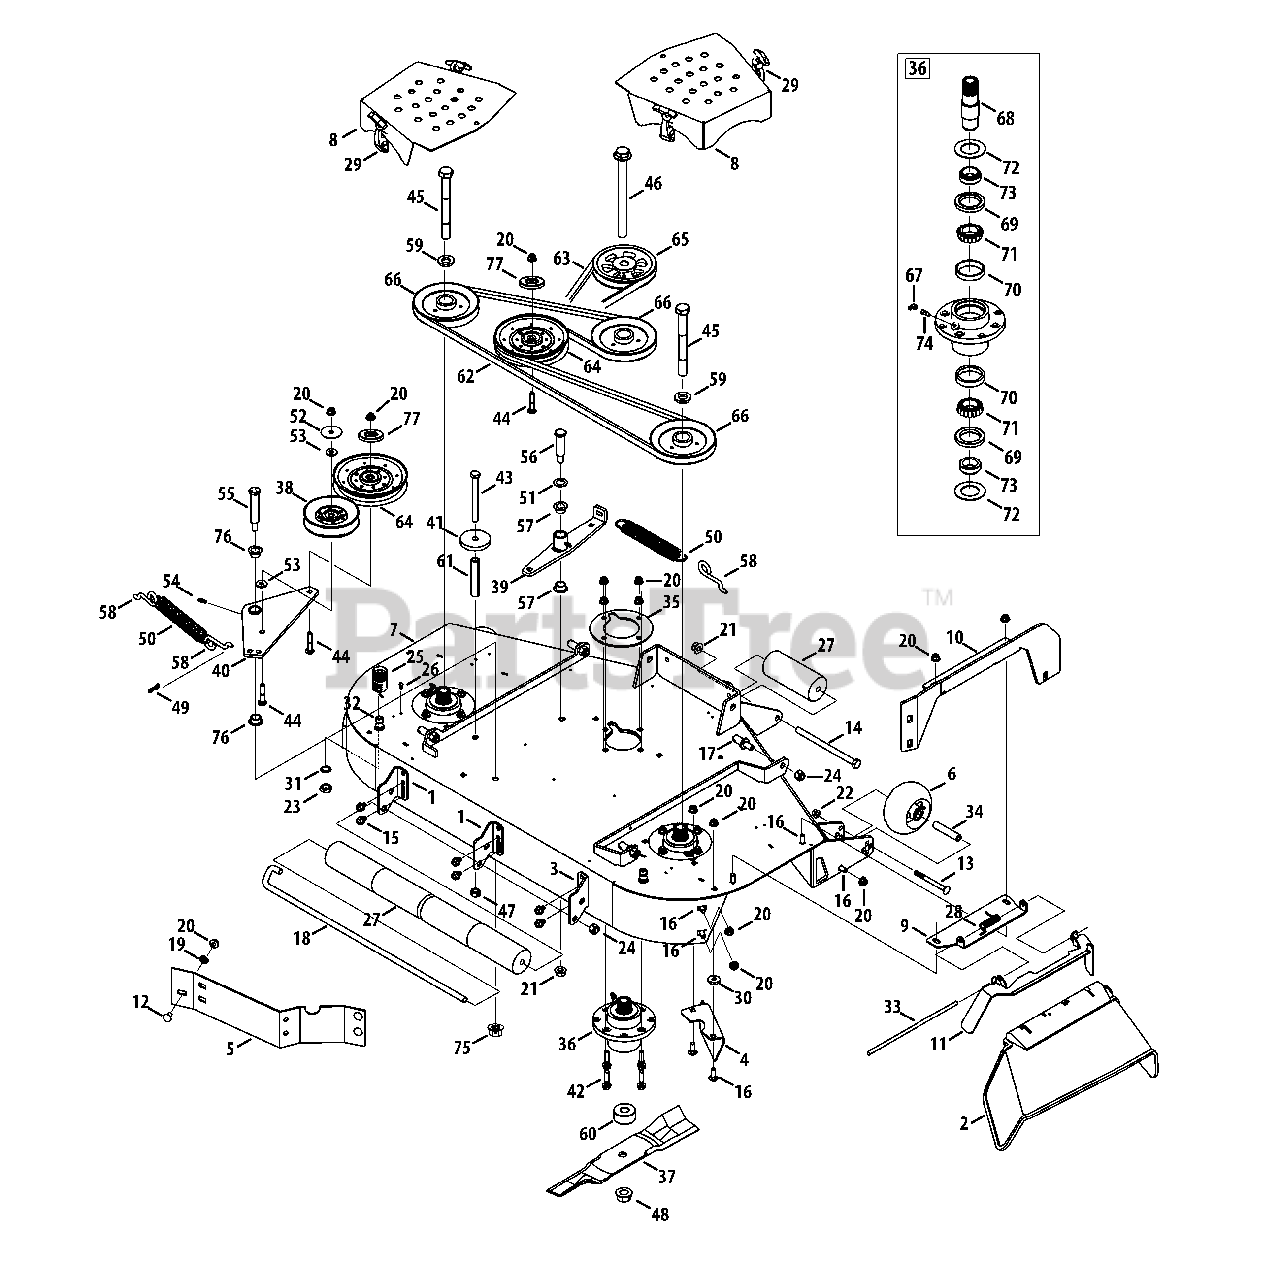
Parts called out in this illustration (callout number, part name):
2	Chute Deflector
5	Baffle, 48" Adjustment
6	Complete Wheel, 5.00 Dia.
7	48" Deck
8	Deck Belt Cover
9	Chute Deflector Bracket
10	Deck Support Plate
11	Chute Extension Bracket
12	Carriage Bolt, 3/8-16 x .750
13	Carriage Bolt, 3/8-16 x 4.00
14	Hex Cap SCrew, 1/2-13 x 7.50
15	Screw, 3/8-16 x .500
16	Carriage Bolt, 3/8-16 x 1.00
17	Pin, 1/2-13 x .625 x 1.2
18	J-Hook w/ Threaded Roller
19	Push Nut, 3/8
20	Nut, 3/8-16, Flangelock
21	Nut, 1/2-13, Flangelock
22	Nut, 3/8-16, Centerlock
23	Hex Nut, M16-1.5
24	Nut, 1/2-13, Hexlock
25	Water Nozzle Adaptor
26	Pop Rivet, 3/16
27	Front Roller
28	Torsion Spring, 0.639 x 2.16
29	T-Handle Latch Draw
30	Washer, .395 x 1.12 x .190
31	Lock Washer, 17 x 23.8 x 1.95
32	Deck Water Nozzle
33	Chute Deflector Rod
34	Wheel Spacer
35	Spindle Support Plate
36	Spindle Assembly
37	Hi-Lift Blade, 17.0
38	Idler Pulley
39	Deck Idler Arm
40	Idler Assembly
41	Spacer, .5375 x 2.75 x .375
42	Carriage Bolt, 3/8-16 x 1.5
43	Hex Cap Screw, 1/2-13 x 5.00
44	Carriage Bolt, 3/8-16 x 2.00
45	Hex Cap Screw, 3/4-16 x 7.00
46	Hex Cap Screw, 3/4-16 x 9.00
47	Nut, 1/2-13, Hexlock
48	Nut, 3/4-16, Flangelock
49	Bow Tie Cotter Pin
50	Extension Spring, 1.248 x 8.5
51	Washer, .793 x 1.24 x .06
52	Washer, .406 x 1.92 x .060
53	Washer, .406 x 1.00 x .105
54	Grease Fitting
55	Shoulder Bolt, 1.0 x 3.15, 5/8-18
56	Shoulder Bolt, .750 x 2.23, 1/2-13
57	Flange Bearing, .75 x .52
58	Spring Rod Hook
59	Spacer, .812 x .218
60	Spacer, .760 x 2.00 x .925
61	Spacer, .405 x .75 x 3.875
64	Idler Pulley
65	Drive Pulley
66	Spindle Pulley
67	Grease Fitting, 45 degree, 1/4-28
68	Spindle Shaft
69	Seal, Oil
70	Cup Bearing
71	Cone Bearing
72	Washer, 1.50 x 2.52 x .075
73	Ring, Seal
74	Straight Adapter Fitting
75	Nut, 5/8-18, Flangelock
76	Flange Bearing, 1.00 x .75
77	Pulley Cap
